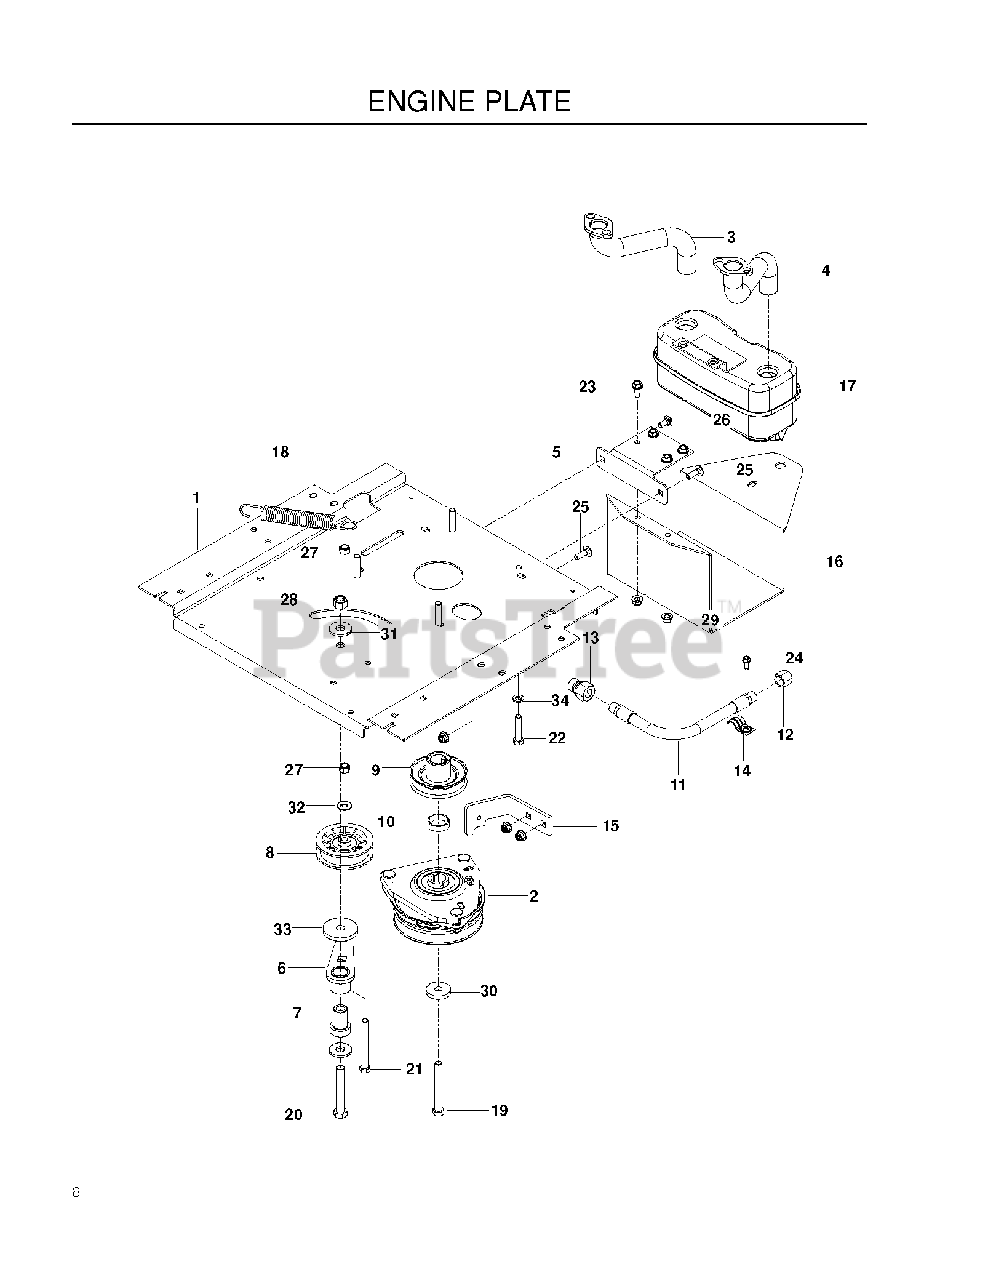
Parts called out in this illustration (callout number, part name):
1	PLATE, ENGINE BLK
2	CLUTCH ELECTRIC
3	TUBE.EXHAUST.LH.FR961/FR730
4	TUBE.EXHAUST.RH.FR961/FR730
5	BRACKET, MUFFLER, BLACK
6	IDLER ARM WELDMENT
7	IDLER SPINDLE
8	PULLEY, IDLER RAKE & ZTR
9	RP PULLEY, ENGINE
10	SPACER, HUB PULLEY
11	OIL DRAIN HOSE
13	ADAPTER, OIL DRAIN
15	CLUTCH STOP OGR BLK
16	GUARD, MUFFLER, BLACK
17	MUFFLER ASM TWIN
18	SPRING, DECK DRIVE
19	HCS 7/16-20 X 2.5 GR8
20	HCS 1/2C X 3 1/4
21	HCS 3/8-16X3 1/2 GR5
22	BOLT, HCS 3/8-16X1-3/4
23	BOLT 5/16-18 X 3/4
24	SCREW 1/4 X 5/8
25	RHSNB 5/16C X 1
26	BOLT 5/16C X 3/4" CARRIAGE
27	NUT 3/8-16 NYLOC
28	RP NUT 1/2-13 HEX NYLOC ZD
29	5/16-18 NYLOC FLANGE NUT
30	CLUTCH, WASHER
31	WASH USS FLAT 1/2
32	WASHER 5/16 FLAT
33	HEAVY WASHER
34	SLW 3/8 STD
